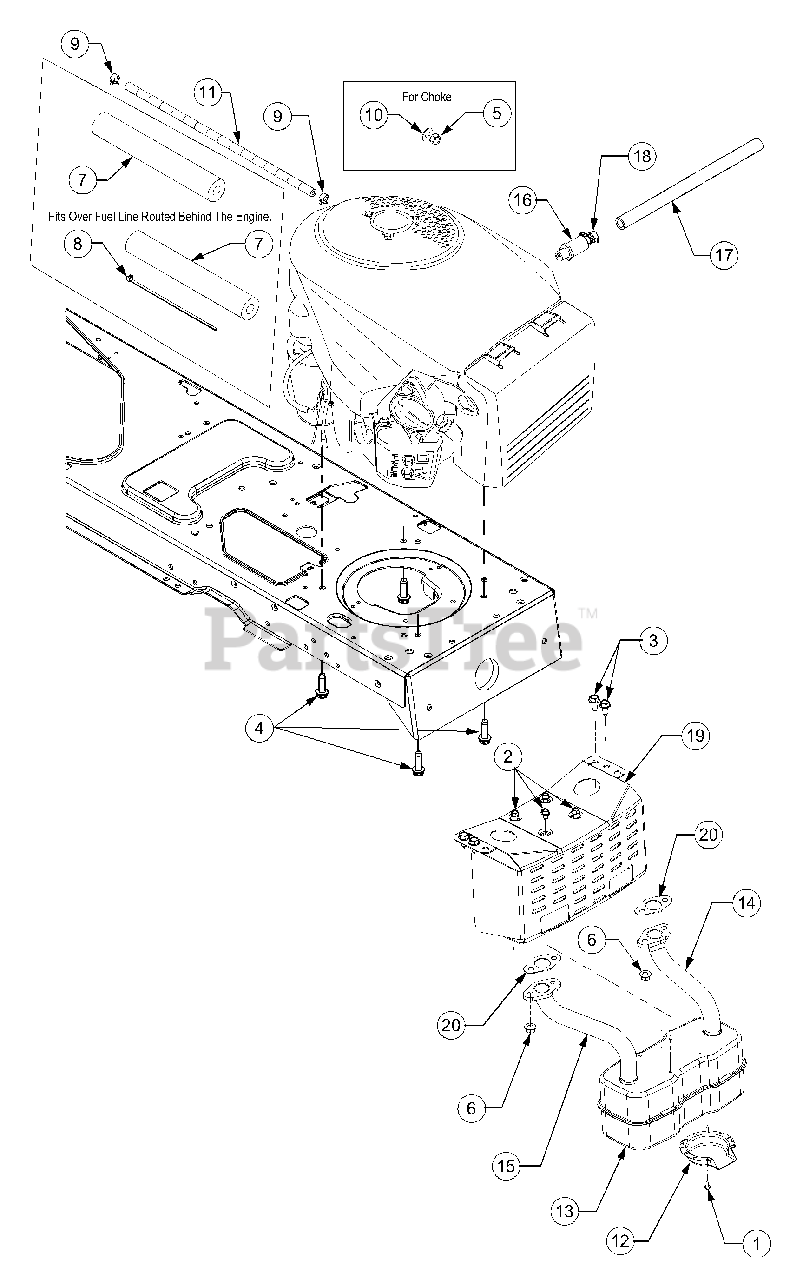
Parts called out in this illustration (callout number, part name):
1	Screw, #8-18, 0.500
2	Screw, Self-tapping, 1/4-20, 0.500
3	Screw, Hx. Wash. Hd. Tapp 5/16-12 x .75
4	Screw, Hx. Wash. Hd. Tapp 3/8-16 x
5	Nut, Hex, 3/8-16, Gr8
6	Nut, M8, 1.25-6h, Flange
7	Foam, .625 x 1.50 x 10.0 Lg
8	Cable, Tie, 3/16 x .05 x 7.4
9	Clamp, Hose, .490 Dia.
10	Washer, Flat, .406 x .875 x .059
11	Hose, Fuel Line
12	Deflector, Muffler
13	Muffler, Dual Inlet
14	Pipe, Exhaust, LH
15	Pipe, Exhaust, RH
16	Drain, Oil
17	Hose, Extension, Oil Drain
18	Cap, Oil, Drain
20	Gasket, Exhaust
